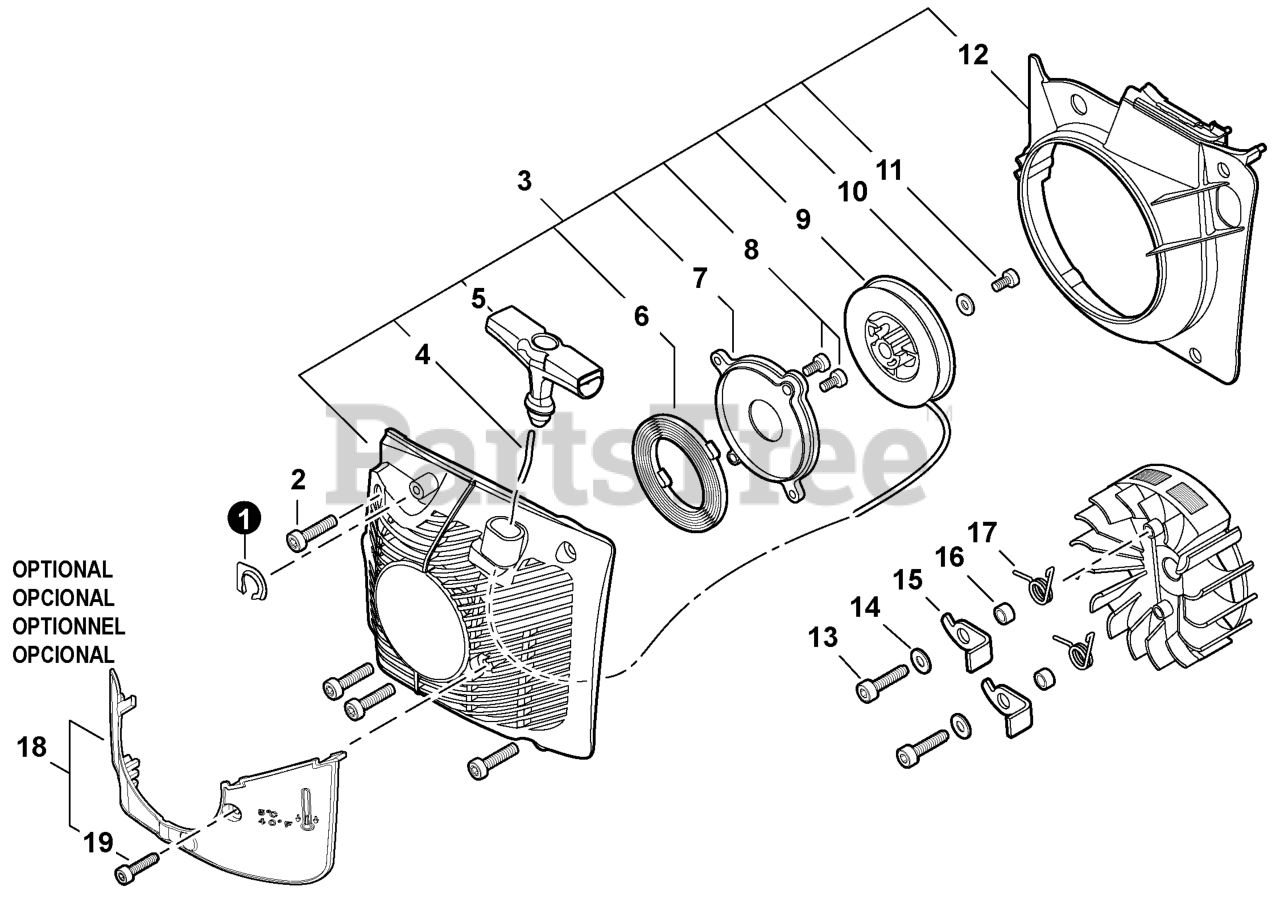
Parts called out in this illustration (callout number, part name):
1	PLATE, EYE
2	BOLT, TORX 5x20
3	STARTER ASSY, RECOIL
4	ROPE, STARTER 4x950
5	GRIP, STARTER
6	SPRING, RECOIL
7	PLATE, STARTER
8	BOLT, TORX 4x12
9	REEL, ROPE
10	WASHER 5.2x16x1.0
11	BOLT, TORX 5x10
12	COVER, FAN
13	BOLT, TORX 5x16
14	WASHER 5.5x12x0.8
15	PAWL, STARTER
16	SPACER 5.2x8x2.1
17	SPRING, TORSION
18	SHIELD KIT - SNOW
19	BOLT, TORX 4x12
